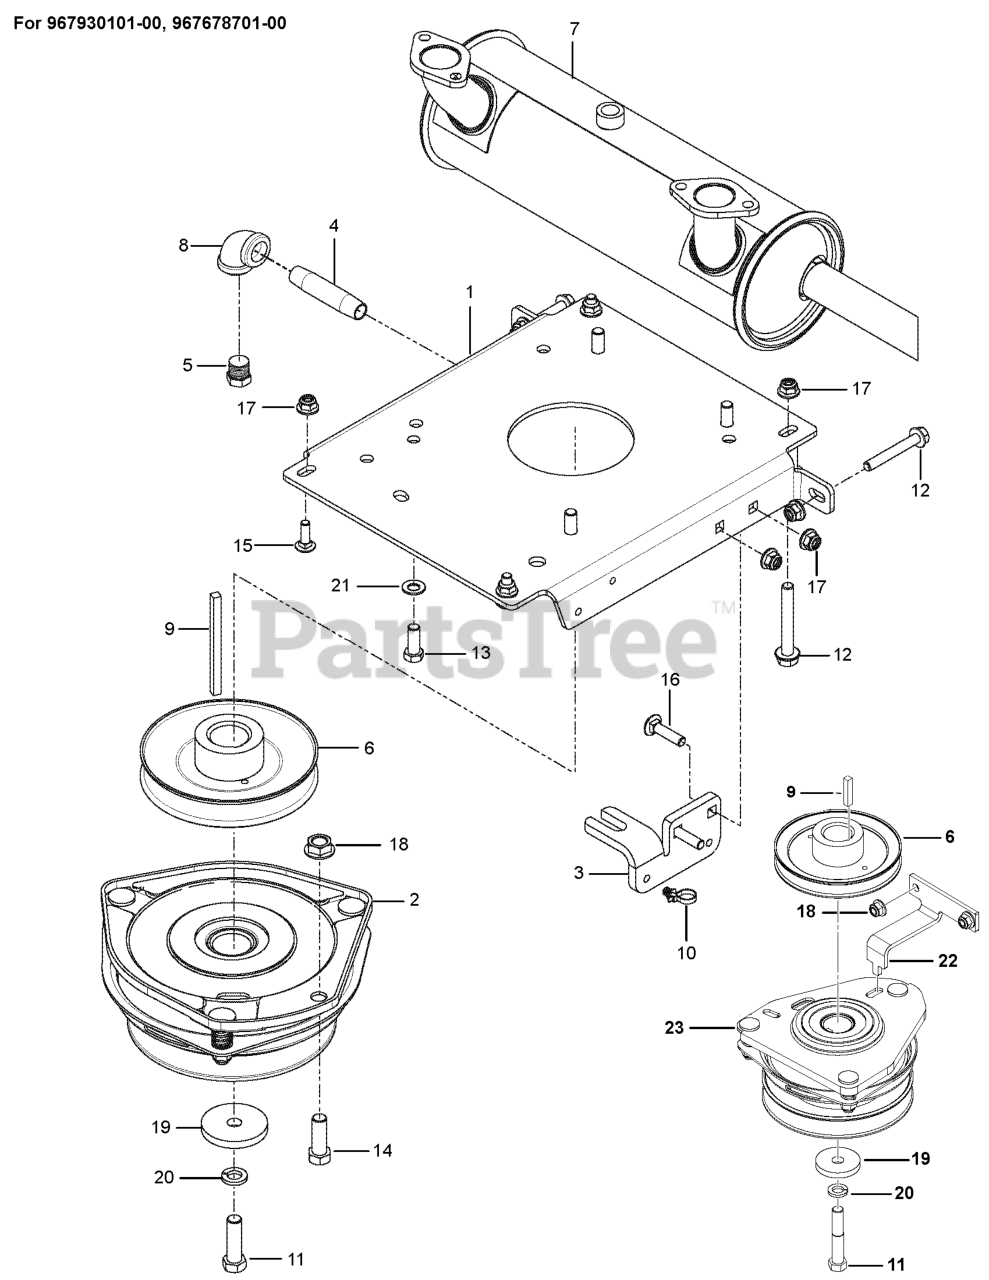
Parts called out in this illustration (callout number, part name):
1	PLATE.PNT.ENGINE.PZ/PZT.EDIP
2	CLUTCH, GT3.5
3	STOP, CLUTCH, OGURA
4	PIPE NIPPLE 3/8 X 3
5	PLUG, DRAIN 3/8 NPTF
6	PULLEY.DRIVE.XMSN
6	PULLEY, ENGINE
7	MUFFLER YAMAHA PN: 7UD-E4711-
8	90 DEG.ELBOW 3/8NPT
9	KEY, 1/4 SQ X 1 1/4
9	KEY, 1/4 SQ X 3.5
10	TIE WRAP, 8-3/8", W/CLIP
11	Bolts
11	CLUTCH BOLT7/16-20X1.5GR5.96HR
12	HHFS 5/16-18 X 2.25 GD 5
13	HCS 3/8-16X1.GRD.5.ZD
14	BOLT FIN HEX 7/16-14 X 1
15	RHSNB 5/16C X 1
16	RHSNB 5/16-18 X 1-1/2 GR 5 ZD
17	5/16-18 NYLOC FLANGE NUT
18	NUT HEXAGON FLANGE 5/16-18 ST
18	NUT 7/16C WHIZ
19	Washers
19	BLADE WASHER
20	Washers
20	WASHER 7/16 LOCK
21	WASHER, 3/8 DISC SPRING SPEC
22	BRACKET.CLUTCH.STOP.PNTX431
23	CLUTCH MZ ZTR GT.48/54"1.125"
